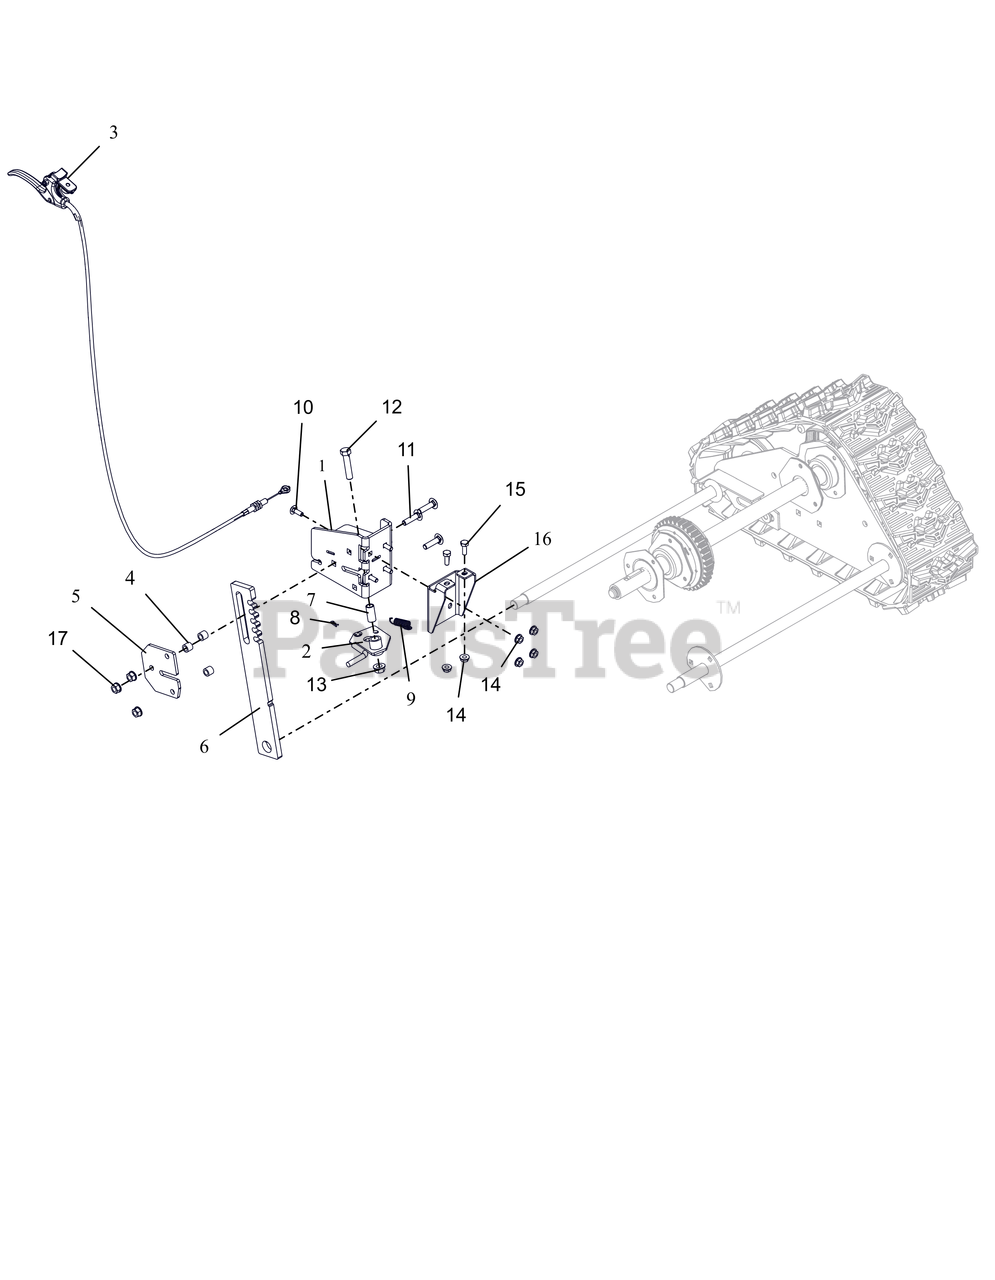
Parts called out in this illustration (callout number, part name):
1	BRACKET,HEIGHT ADJUSTER-DELUXE
2	LOCK,HEIGHT ADJUSTER TRIGGER
3	CABLE, TRACK REMOTE
4	SPACER .50 X .32 X .42
5	PLATE, HEIGHT ADJUSTER
6	STOP, HEIGHT
7	BSHG-SLV .385X.500X1.045
8	PIN, HAIR #178 .06X.77 ZCC
9	SPRING-EXT .047 X .438 X 1.85
10	BLT, RHSN .25-20X.750 G5 ZCC
11	BLT, RHSSN.31-18X1.25 G5 ZCC
12	BLT, HEX .38-16X1.75 G5 ZCC
13	NUT-LK-CTR-FLG .375-16 GF ZCC
14	NUT-LK-CTR-FLG .25-20 ZC120
15	BLT, HEX .25-20X.75 G5 ZCC
16	BRACKET, REINFORCEMENT
17	NUT-LK-TOP-FLG .312-18 GF ZCC
